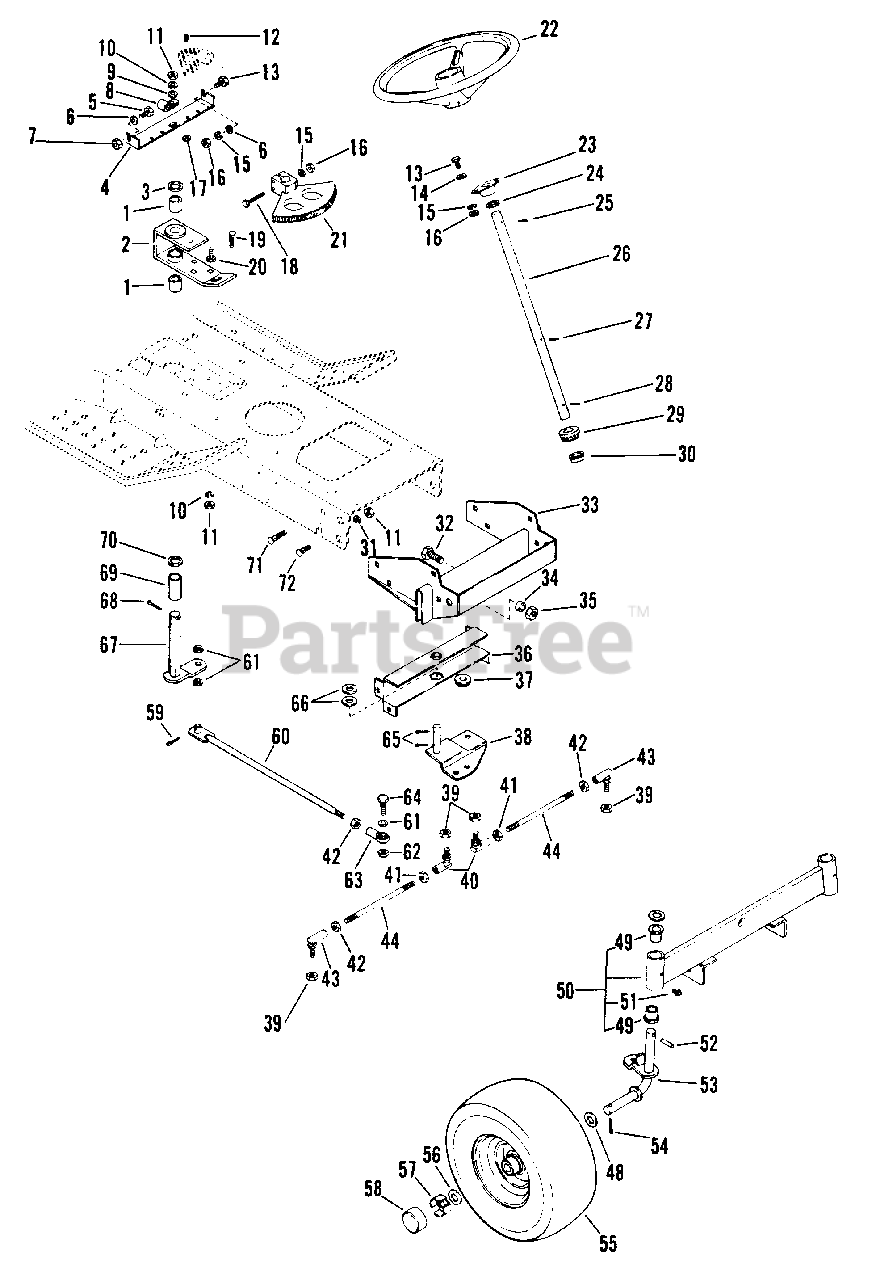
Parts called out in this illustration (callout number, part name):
1	BUSHING, SLEEVE
2	BRACKET, STEERING
3	WASHER
4	BRACE
5	BOLT, HEX 5/16-18X1.25
6	WASHER, FLAT .312X.734X.065
7	NUT, LOCK 5/16-18
8	CLIP
9	WASHER, FLAT .406X.812X.065
10	WASHER, LOCK 3/8 REG.
11	NUT, HEX 3/8-16
12	SCREW, MACHINE 10-24X.625 PHD
13	BOLT, HEX 5/16-18X.75
14	WASHER, FLAT .312X.734X.065
15	WASHER, LOCK 5/16 SP.
16	NUT, HEX 5/16-18
17	NUT, KEPS 10-24
18	BOLT, HEX 5/16-18X1.75
19	BOLT, 3/8-16X1.25 RD HD SQ NK
20	BOLT, HEX 3/8-16X1.00
21	GEAR, STEERING BEVEL
22	WHEEL, STEERING
23	BEARING, FLANGE
24	WASHER, FLAT .813X1.37X.100
25	PIN, SPRING .250X1.750
26	COLUMN, STEERING
27	PIN, SPRING .187X1.250
28	ROLLER, NEEDLE
29	GEAR, STEERING PINION
30	BUSHING, FLANGE
31	WASHER, LOCK 3/8 REG.
32	BOLT, HEX 1/2-13X1.25
33	SUPPORT, FRONT AXLE
34	SPACER
35	NUT, LOCK 1/2-13
36	CHANNEL, STEERING PIVOT
37	BUSHING, FLANGE
38	PIVOT, STEERING
39	NUT, LOCK 3/8-24
40	JOINT, BALL L.H.
41	NUT, HEX 3/8-24 L.H. THREAD
42	NUT, HEX 3/8-24
43	JOINT, BALL R.H.
44	ROD, TIE
45	PIN, SPRING .125X1.000
46	PIN, COTTER .125X1.00
47	WASHER, FLAT .531X1.000X.063
48	WASHER, FLAT .813X1.37X.100
49	BUSHING, FLANGE
50	WELDMENT, FRONT AXLE
51	FITTING, ZERK
52	PIN, SPRING
53	SPINDLE, L.H.
53	SPINDLE, R.H.
54	PIN, COTTER THD 1/4
55	TIRE AND WHEEL, FRONT
55	TIRE AND WHEEL, REAR
56	WASHER, FLAT .813X1.37X.100
57	CUP, SPINDLE
58	CAP, HUB
59	PIN, COTTER .125X1.00
60	LINK, DRAG
61	WASHER, FLAT .531X1.000X.063
62	NUT, LOCK 3/8-16
63	END, ROD
64	BOLT, HEX 3/8-16X1.25
65	PIN, COTTER .125X1.25
66	WASHER, FLAT .656X1.312X.095
67	ARM AND SHAFT
68	PIN, COTTER .187X1.25
69	SPACER
70	WASHER, FLAT .938X1.750X.134
71	BOLT, 3/8-16X1.00 RD HD SQ NK
72	BOLT, CARRIAGE 3/8-16X.75
NS	BEARING, BALL .750X1.375
